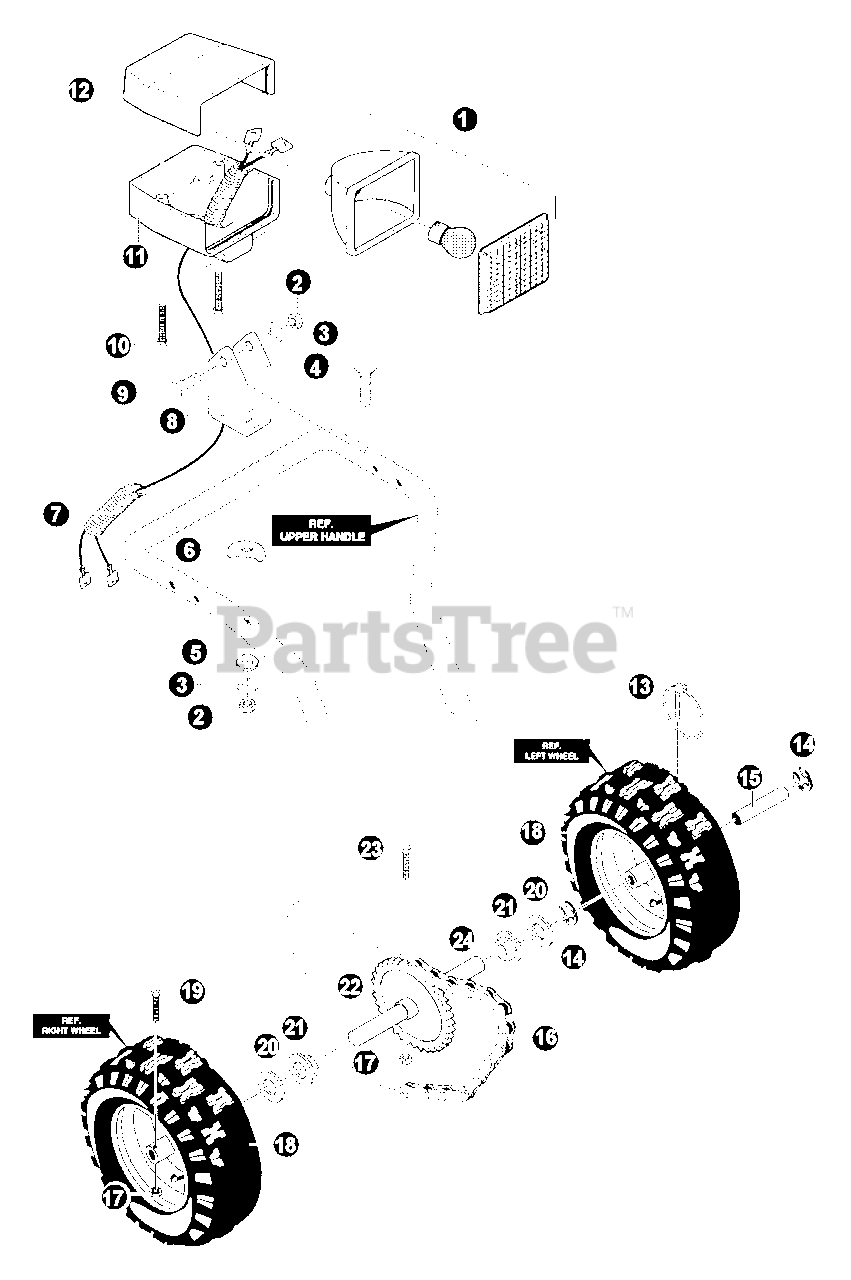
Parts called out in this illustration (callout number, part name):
1	HOUSING, HEAD LIGHT
2	NUT - 5/16-18
3	LOCKWASHER
4	BOLT, 5/16-18X2.25
5	WASHER
6	WASHER - WAVE,
7	WIRING, HARNESS ASSY
8	BRACKET, HEADLIGHT
9	SCREW - 5/16-18 X 2"
10	SCREW - 8 X 1-3/4"
11	CASE, HEADLIGHT - LOWER
12	HOUSING, HEADLIGHT UPPER
13	PIN, KLIK
14	RING, RETAINING
15	BUSHING, WHEEL 4" LG
16	CHAIN, ROLLER 420X41
17	NUT - 1/4-20
18	WHEEL ASSY
19	SCREW - 1/4-20 X 1.75"
20	WASHER
21	BEARING, FLANGE
22	SPROCKET, HUB
23	SCREW - 1/4-20 X 2.25"
24	SHAFT, AXLE 6.15
